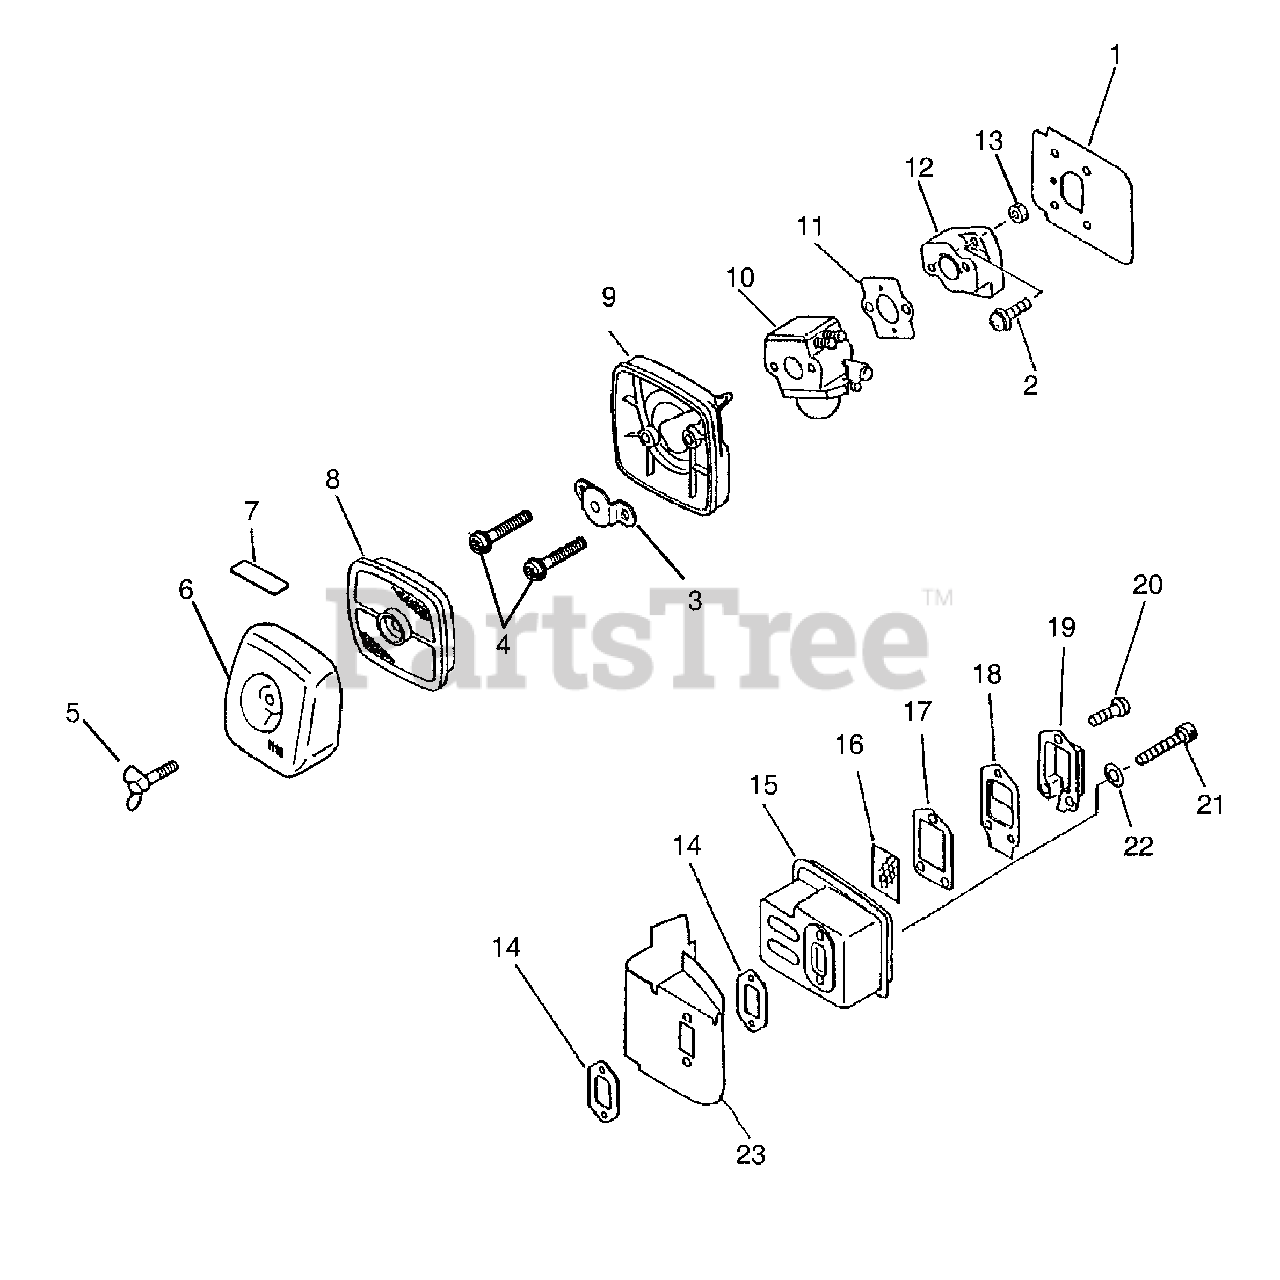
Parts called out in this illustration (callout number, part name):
1	HEAT SHIELD, INTAKE
2	SCREW 5×20
3	PLATE, PREVENT
4	SCREW 5×65
5	BOLT, WING 5×20
6	COVER, AIR FILTER - GRAY
7	LABEL, CHOKE
8	FILTER, AIR
8	FILTER, AIR - SINGLE LAYER
9	CASE, AIR FILTER - GRAY
10	CARBURETOR - C1U-K51
11	GASKET, INTAKE
12	INSULATOR, INTAKE
13	NUT M5
14	GASKET, EXHAUST
16	SCREEN, SPARK ARRESTER
17	GASKET, EXHAUST
18	GUIDE, EXHAUST
19	GUIDE, EXHAUST - INNER
20	SCREW 4×10
21	BOLT 5×55
22	WASHER, FLAT 5.5×10×0.8
23	HEAT SHIELD, EXHAUST
